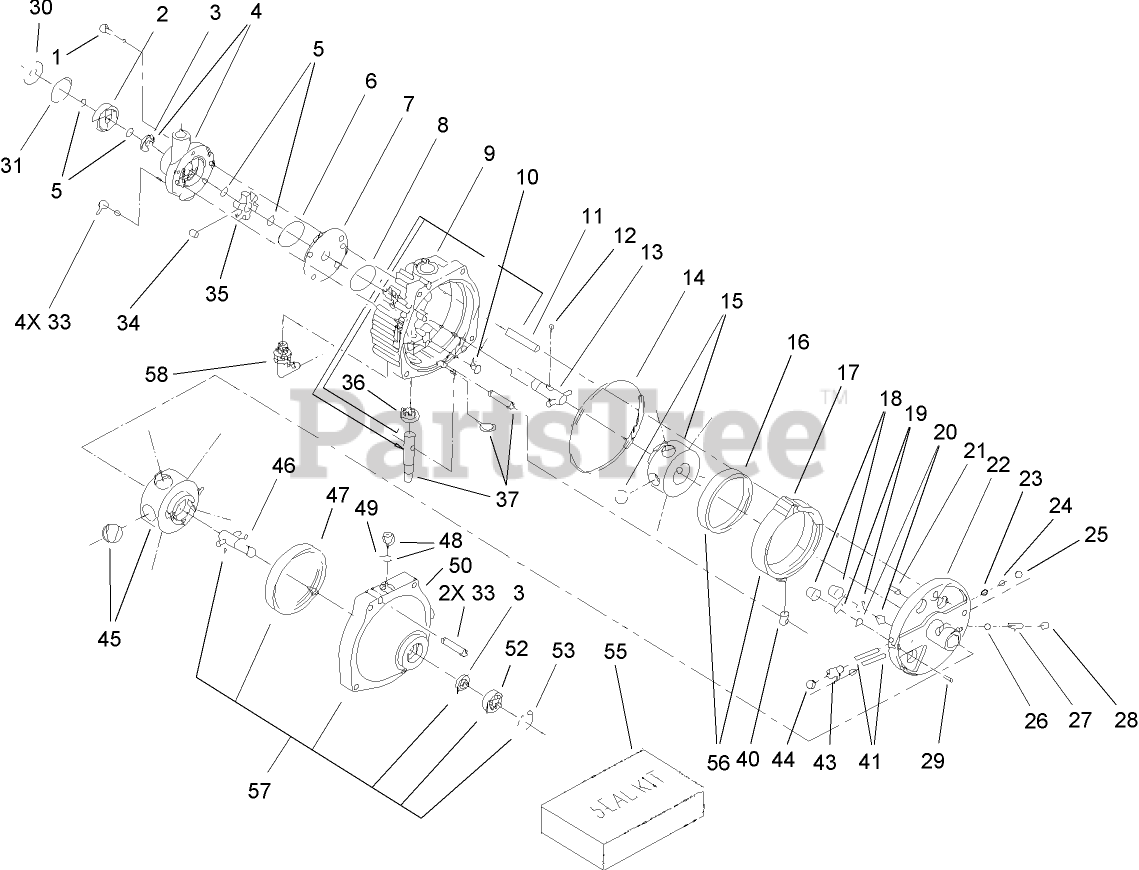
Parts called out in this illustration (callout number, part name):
1	CAPSCREW
2	BEARING
3	SEAL-OIL
4	PUMP ASM
7	PLATE
9	COVER SUB ASM
10	BUTTON
13	SHAFT
15	ROTOR
16	PUMP-RACE
17	RING-CAM
18	PISTON
20	O-RING
22	PINTLE
27	SPRING
30	SHIELD-GRASS
31	RETAINING-RING
33	SCREW-HH
35	CARRIER
36	SEAL-OIL
37	SHAFT KIT
40	INSERT
41	SPRING
45	ROTOR
46	SHAFT
48	PLUG ASM
49	O-RING
50	Body
52	BEARING-BALL (INPUT)
55	SEAL KIT
56	CAM RING ASM
57	Body ASM
58	FITTING-90 DEGEE
